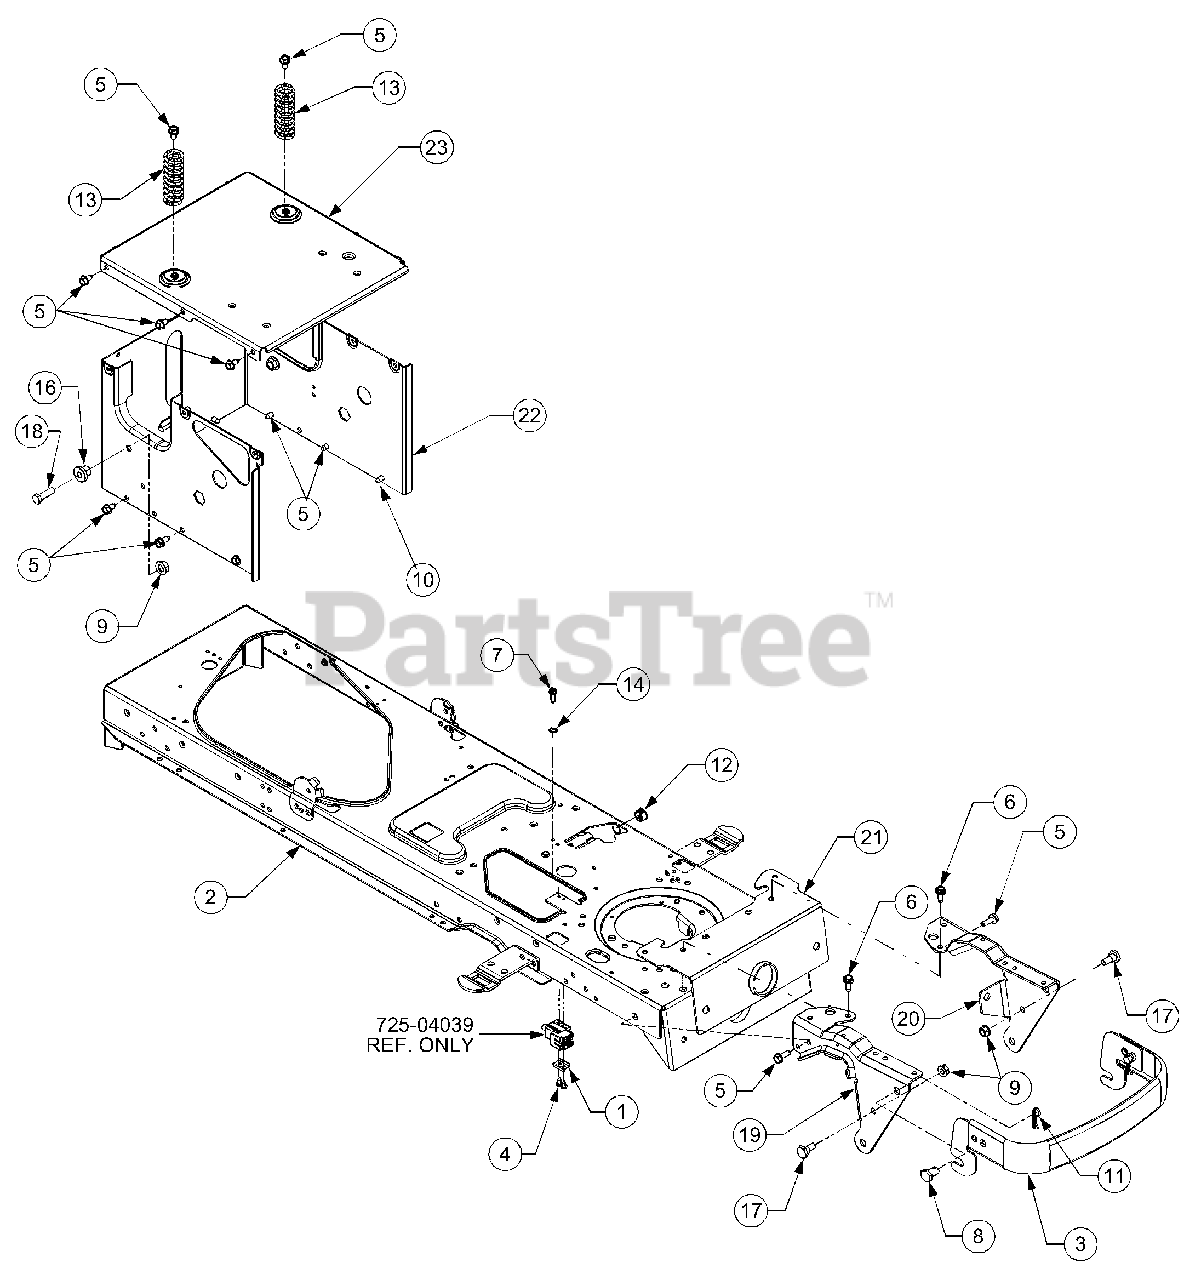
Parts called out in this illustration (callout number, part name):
1	Plate, Switch
5	Screw, Self-tapping, 5/16-18, 0.75
6	Screw, 5/16-18, 0.750
7	Screw, Hex Wash. Hd. Tapp, 1/4-20 x 0.625
8	Pin, Clevis, .50 Dia x .78 Lg
9	Nut, Nylon Lock, 3/8-16
10	Screw, Hex Wash. Tapp, 5/16-18 x .5
11	Pin, Click, .092 x 1.64 Lg
12	Snap Bushing
13	Spring, Compression, 1.28 OD x 3.125 Lg
14	Washer, Lock, Ext 1/4
16	Shoulder Spacer
17	Shoulder Screw, 3/8-16
18	Hex Screw 3/8-16 x 1.25
22	Frame, Upper, Cub 1500
